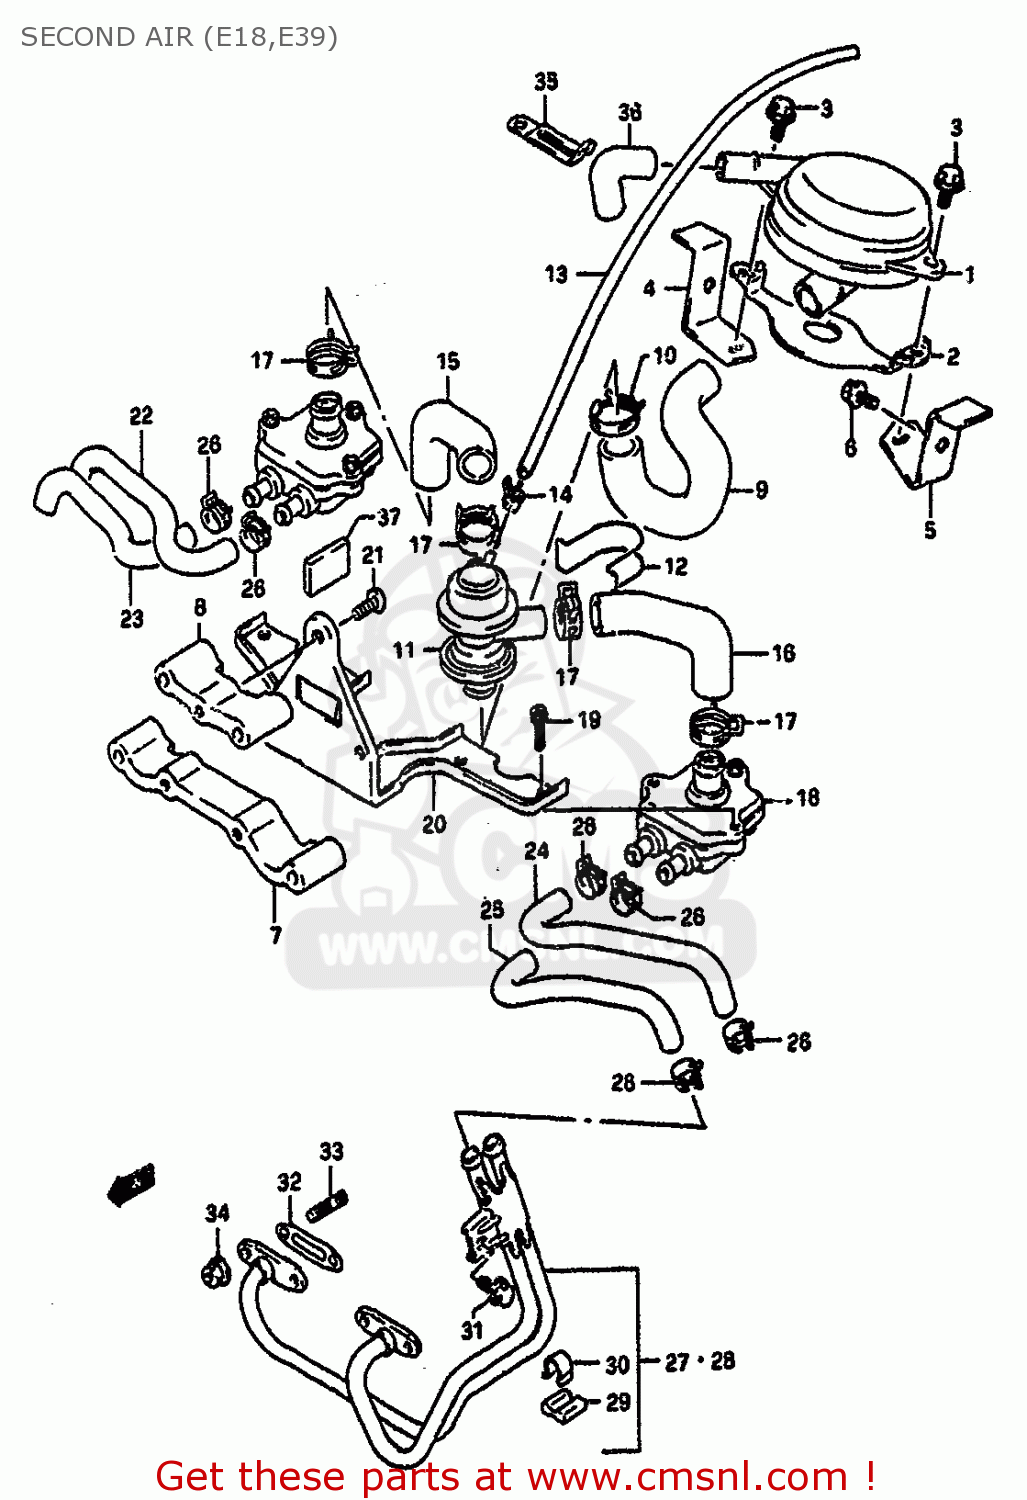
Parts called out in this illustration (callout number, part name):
1	CLEANER ASSEMBLY,SECOND AIR
2	HOLDER,SECOND AIR CLEANER
3	BOLT
4	BRACKET,SECOND AIR CLEANER
5	BRACKET,SECOND AIR CLEANER
6	BOLT
7	SPACER,SECOND AIR BRACKET,LOWER
8	SPACER,SECOND AIR BRACKET,UPPER
9	HOSE,SECOND AIR NO.3
10	CLIP
11	VALVE ASSEMBLY,AIR SWITCH
12	CLAMP,SWITCHING VALVE
13	HOSE
14	CLAMP
15	HOSE,SECOND AIR NO.2,RIGHT
16	HOSE,SECOND AIR NO.2,LEFT
17	CLIP
18	VALVE ASSY,2ND AIR REED
19	BOLT
20	BRACKET,SECOND AIR VALVE
21	SCREW
22	HOSE,SECOND AIR NO.1,RIGHT,INLET
23	HOSE,SECOND AIR NO.1,RIGHT,OUTLET
24	HOSE,SECOND AIR NO.1,LEFT,INLET
25	HOSE,SECOND AIR NO.1,LEFT,OUTLET
26	CLIP
27	PIPE ASSEMBLY,SECOND AIR,RIGHT
28	PIPE ASSEMBLY,SECOND AIR,LEFT
29	(CA) CUSHION
30	(CA) CLIP,SECOND AIR PIPE
31	BOLT 6X12
32	GASKET,SECOND AIR PIPE (NAS)
33	STUD BOLT
34	NUT 6MM
35	CLAMP
36	(CA) HOSE,SECOND AIR CLEANER
37	CUSHION
